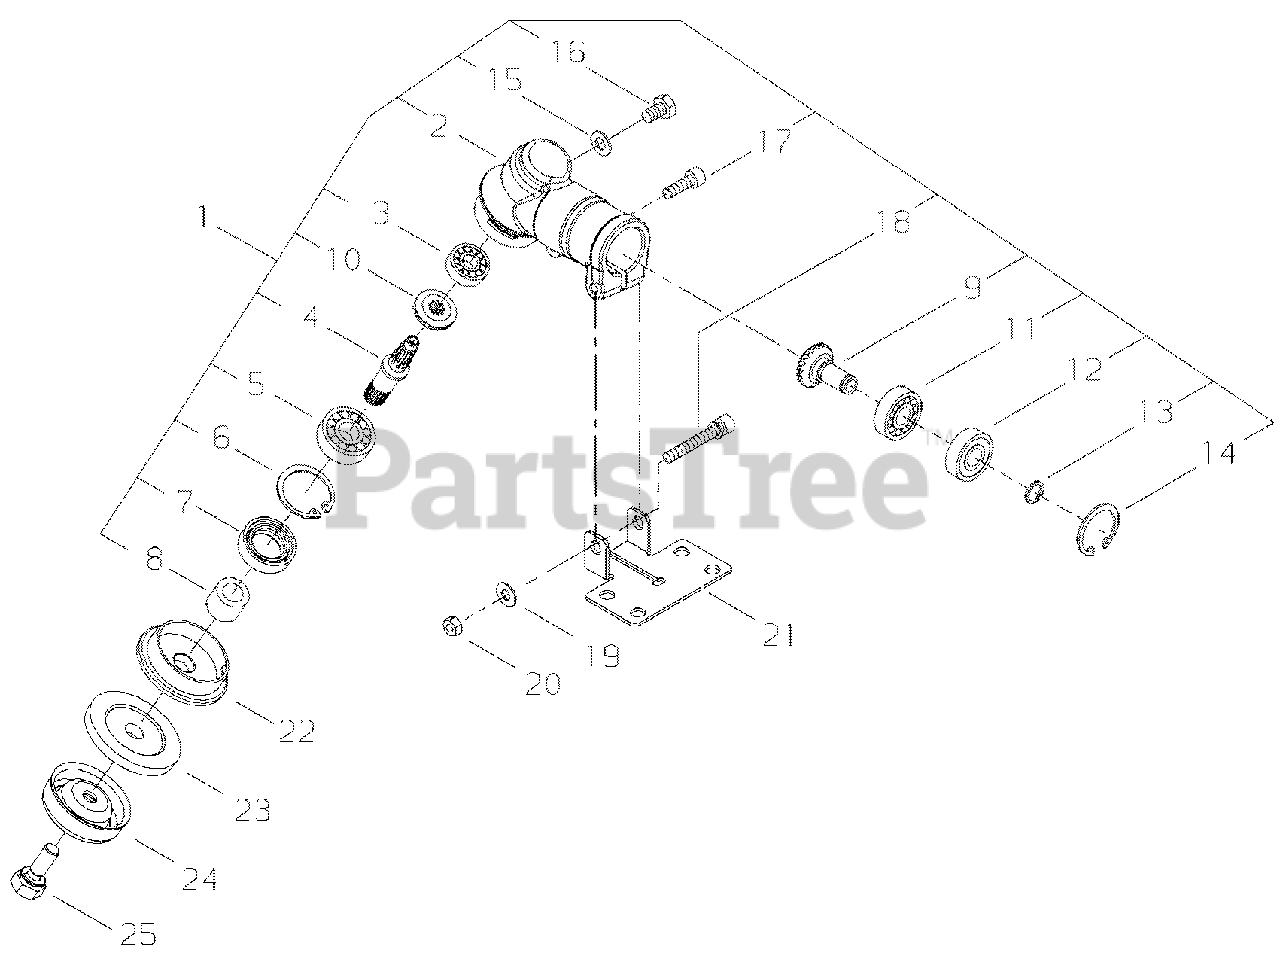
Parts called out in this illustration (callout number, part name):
1	GEAR CASE ASSY
2	HOUSING, GEAR CASE
3	BEARING, BALL 626 MOS
4	SHAFT, GEAR
5	BEARING, BALL 6000 MOS
6	RING, SNAP Ø26
7	SEAL, OIL
8	SPACER
9	GEAR, PINION
10	GEAR, BEVEL
11	BEARING, BALL 609 MOS
12	BEARING, BALL 609Z MOS
13	RING, SNAP Ø9
14	RING, SNAP Ø24
15	WASHER 6.5×11.5×0.8
16	BOLT M6×10
17	BOLT M5×10
18	BOLT M5×40
19	WASHER 5 MM
20	NUT M5
21	PLATE, SHIELD MOUNTING
22	PLATE, ADAPTOR - UPPER
23	PLATE, ADAPTOR - LOWER
24	GUARD, BOLT
25	BOLT M7×20
